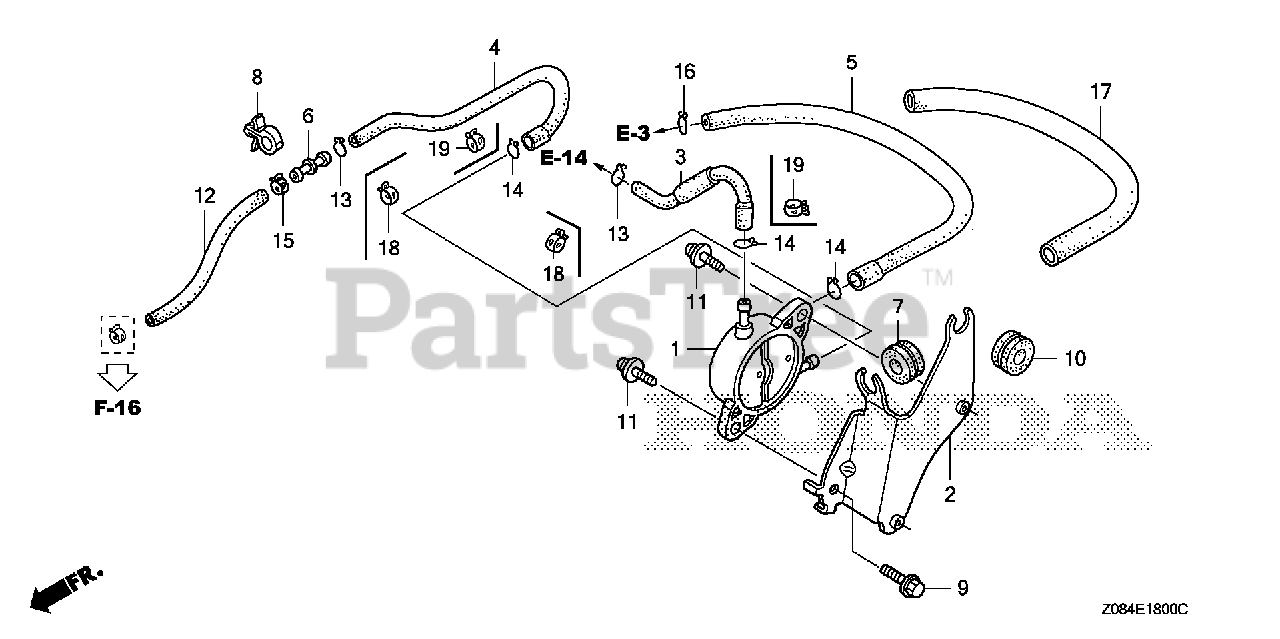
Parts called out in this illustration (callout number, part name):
1	PUMP ASSY., FUEL
1	PUMP ASSY., FUEL (MSDS)
2	STAY, FUEL PUMP
3	TUBE, FUEL (A)
4	TUBE B, FUEL
5	TUBE, DIAPHRAGM
6	JOINT, FUEL TUBE
7	GROMMET, RESERVE TANK
8	CLIP, IGNITION WIRE (BLACK IN.D=7.0MM)
9	BOLT, FLANGE (6X14) (CT200)
10	GROMMET, PUMP STAY
11	SCREW-WASHER (6X16)
12	BULK HOSE, FUEL (4.5X3000) (4.5X190)
13	CLIP, TUBE (B8)
14	CLIP, TUBE (B10)
15	CLAMP, TUBE (D8.5)
16	CLIP, TUBE (C9)
17	BULK HOSE, VINYL (9X11X3000) (9X11X150)
